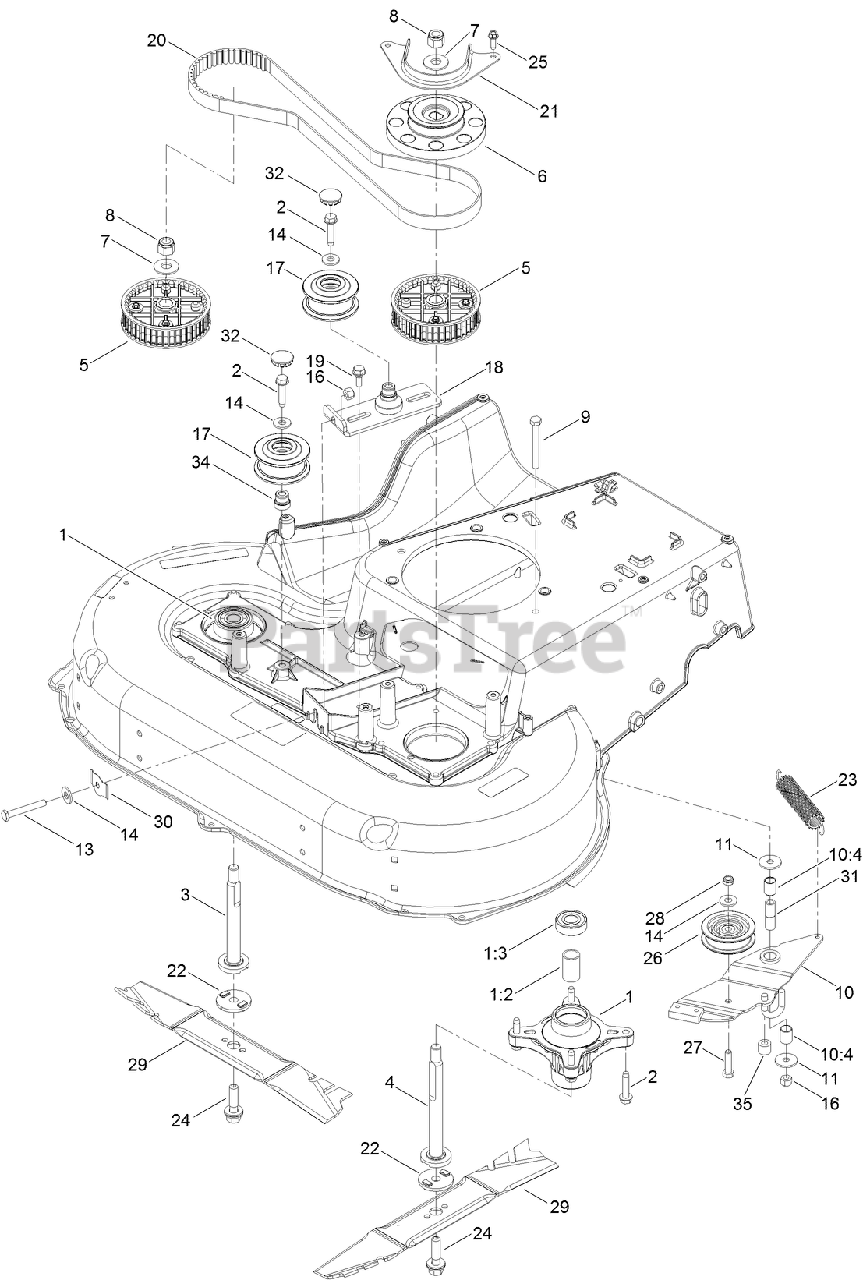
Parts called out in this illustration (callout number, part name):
1	SPINDLE ASM
1:2	SPACER
1:3	BEARING-BALL
2	SCREW-HWH
3	SHAFT-SPINDLE
4	SHAFT-SPINDLE
5	SPROCKET
6	PULLEY-BRAKE, SPINDLE
7	WASHER-SPRING
8	NUT-HEX
9	SCREW-HH
10	BRAKE ARM ASM
10:4	Bushing-Sleeve
11	WASHER-PIVOT
13	BOLT-TAP, HH
14	WASHER-FLAT
16	NUT-LOCK, NI
17	PULLEYS AND IDLER KIT
18	BRACKET-IDLER
19	SCREW-SHOULDER, HHF
20	BELT-SYNCHRONOUS
21	GUIDE-BELT, SPINDLE
22	ADAPTER-BLADE
23	SPRING-EXTENSION, BRAKE
24	BOLT-BLADE
25	SCREW-HWHTF
26	PULLEY-IDLER
27	SCREW-HH
28	NUT-LOCK, NI
29	BLADE-ROTARY
30	SPRING-FLAT
31	Spacer-Brake
32	PLUG-BUTTON
34	ADAPTER-BORE
35	HOSE-COOLANT
